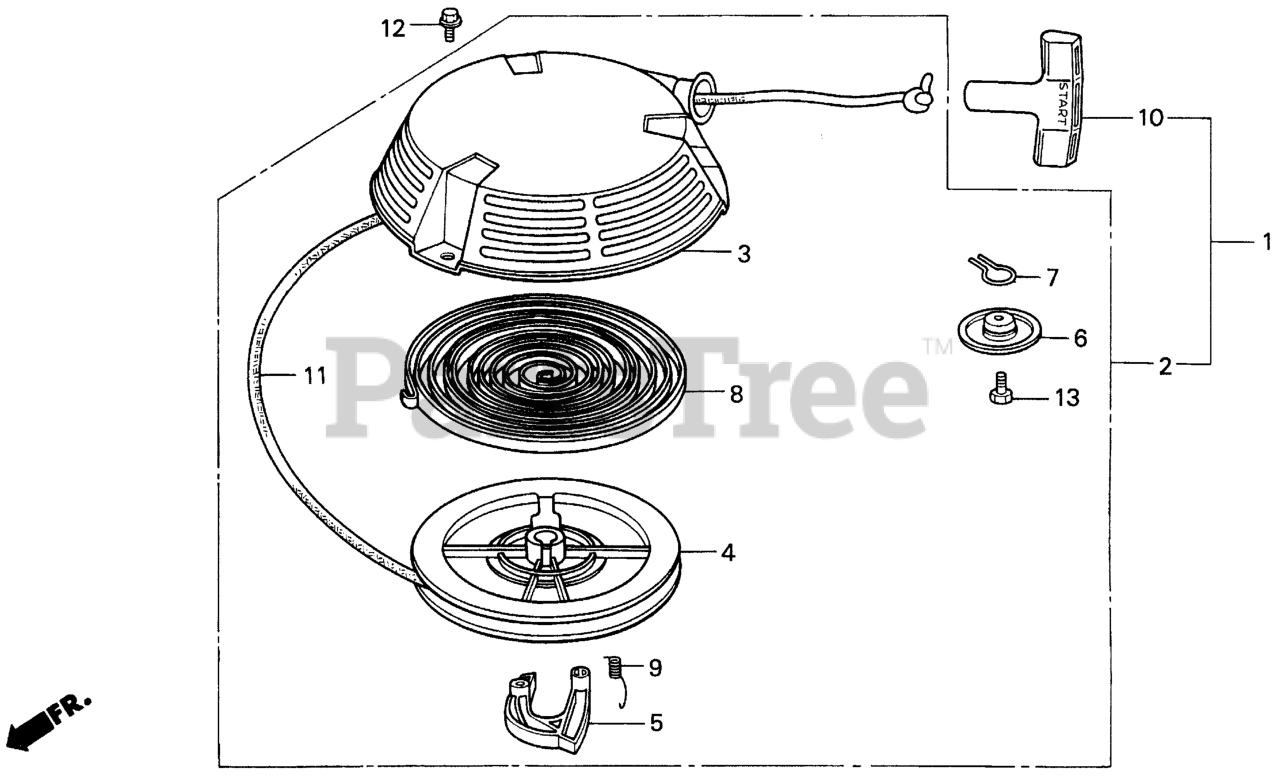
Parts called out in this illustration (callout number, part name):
1	STARTER ASSY., RECOIL *R280* (POWER RED)
3	CASE, RECOIL STARTER *R8* (Honda Code 3352754). (BRIGHT RED)
4	PULLEY, RECOIL STARTER
5	RATCHET, STARTER
6	PLATE, FRICTION
7	SPRING, FRICTION
8	SPRING, RECOIL STARTER
9	SPRING, RETURN
10	KNOB, RECOIL STARTER
11	ROPE, RECOIL STARTER (#4X55")
11	ROPE, LONG (55")
12	BOLT, FLANGE (6X8)
13	BOLT, HEX. (6X20)
